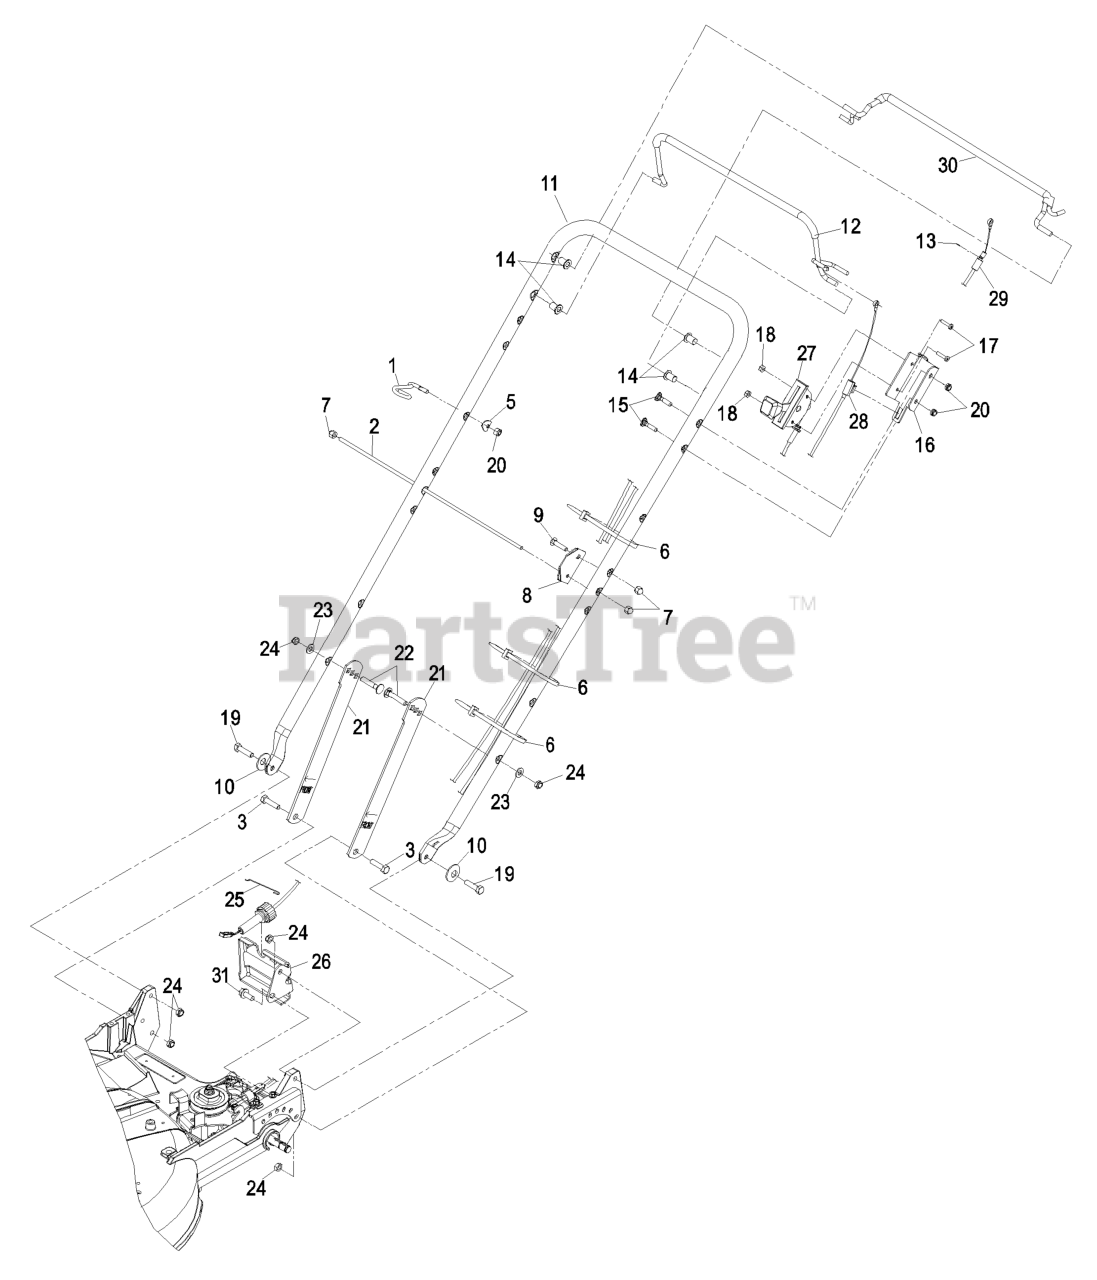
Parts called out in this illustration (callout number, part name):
1	GUIDE-ROPE
2	ROD, BAG SUPPORT
3	SCREW-HH
4	SCREW-HH
5	WASHER
6	TIE-CABLE
7	NUT-CAP
9	SCREW-CARR
10	WASHER-BELLEVILLE
11	HANDLE M21
14	BUSHING
15	BOLT-HANDLE
16	BRACKET, THROTTLE
17	SCREW-PPH
18	NUT-LOCK, NI
19	SCREW-HH
20	NUT-LOCK, NI
21	LATCH,HANDLE
22	BOLT-CARR
23	WASHER-PLAIN
24	NUT-LOCK, NI
25	RETAINER-CABLE
26	BRACKET-ADJUSTMENT, TRACT
27	CABLE,THROTTLE KAWASAKI
28	CABLE,BRAKE KAWASAKI
29	CABLE,TRACTION M21
30	ASM,TRACTION BAIL W/GRIP
31	Screw-HWH 5/16-18 X 3/4 Tf
